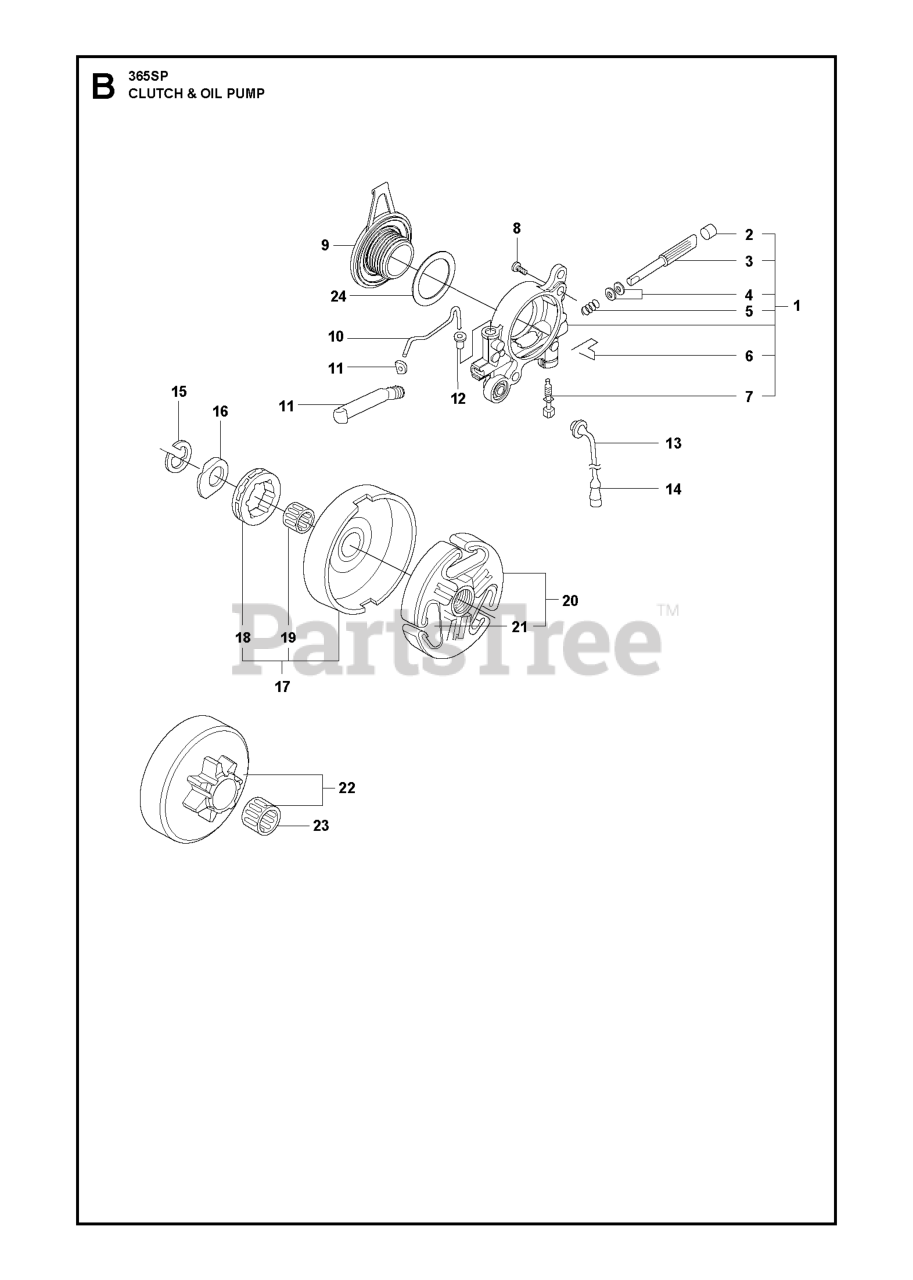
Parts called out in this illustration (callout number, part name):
1	OIL PUMP
3	PUMP PISTON
4	WASHER 6.1X9
6	SPRING CLIP
8	SCREW ITXSCM M5X16 T27 12.9 T
9	PUMP PINION
11	OIL PRESSURE HOSE
11	GROMMET
14	OIL SCREEN
15	RETAINING RING
17	CLUTCH DRUM ASSY
18	68210 RIMSPROCKET
18	22273 Sprocket 3/8"x8T
19	CLUTCH DRUM BEARING
20	CLUTCH ASSY M14X1.25-6H
22	CLUTCH DRUM
23	CLUTCH DRUM BEARING
